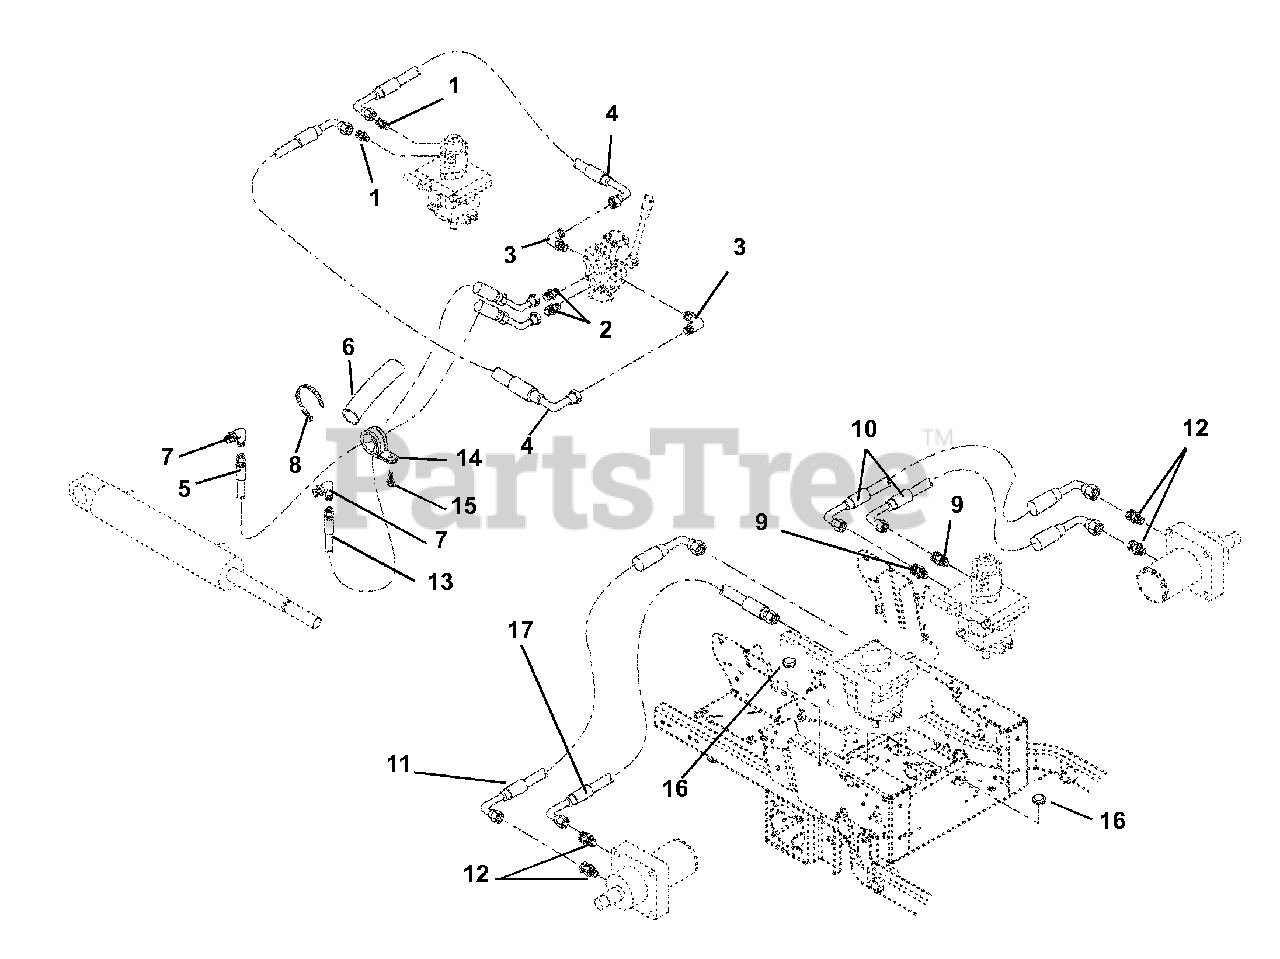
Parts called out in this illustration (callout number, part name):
1	Fitting, Hydraulic (992077, 078, 079, 080, 081, 082, 310, 311)
2	Fitting, Hydraulic (992077, 078, 079, 080, 081, 082, 310, 311)
3	Fitting, Hydraulic Elbow (992077, 078, 079, 080, 081, 082, 310, 311)
4	Hose, Hydraulic (992077, 078, 079, 080, 081, 082, 310, 311)
5	Hose, Hydraulic (992077, 078, 079, 080, 081, 082, 310, 311)
6	Sleeve, Protective 24" (992077, 078, 079, 080, 081, 082, 310, 311)
7	Fitting, Hydraulic Elbow (992077, 078, 079, 080, 081, 082, 310, 311)
8	Cable Tie (992077, 078, 079, 080, 081, 082, 310, 311)
9	Adapter, Hydraulic
10	Hose, Hydraulic
11	Hose, Hydraulic
12	Adapter, Hydraulic
13	Hose, Hydraulic (992077, 078, 079, 080, 081, 082, 310, 311)
14	Clamp, Steel 1.0 (992077, 078, 079, 080, 081, 082, 310, 311)
15	Screw-Tapping .25-20 X .50 Hex Washer Head Thread (992077, 078, 079, 080, 081, 082, 310, 311)
16	Grommet, 1.25
17	Hose, Hydraulic
